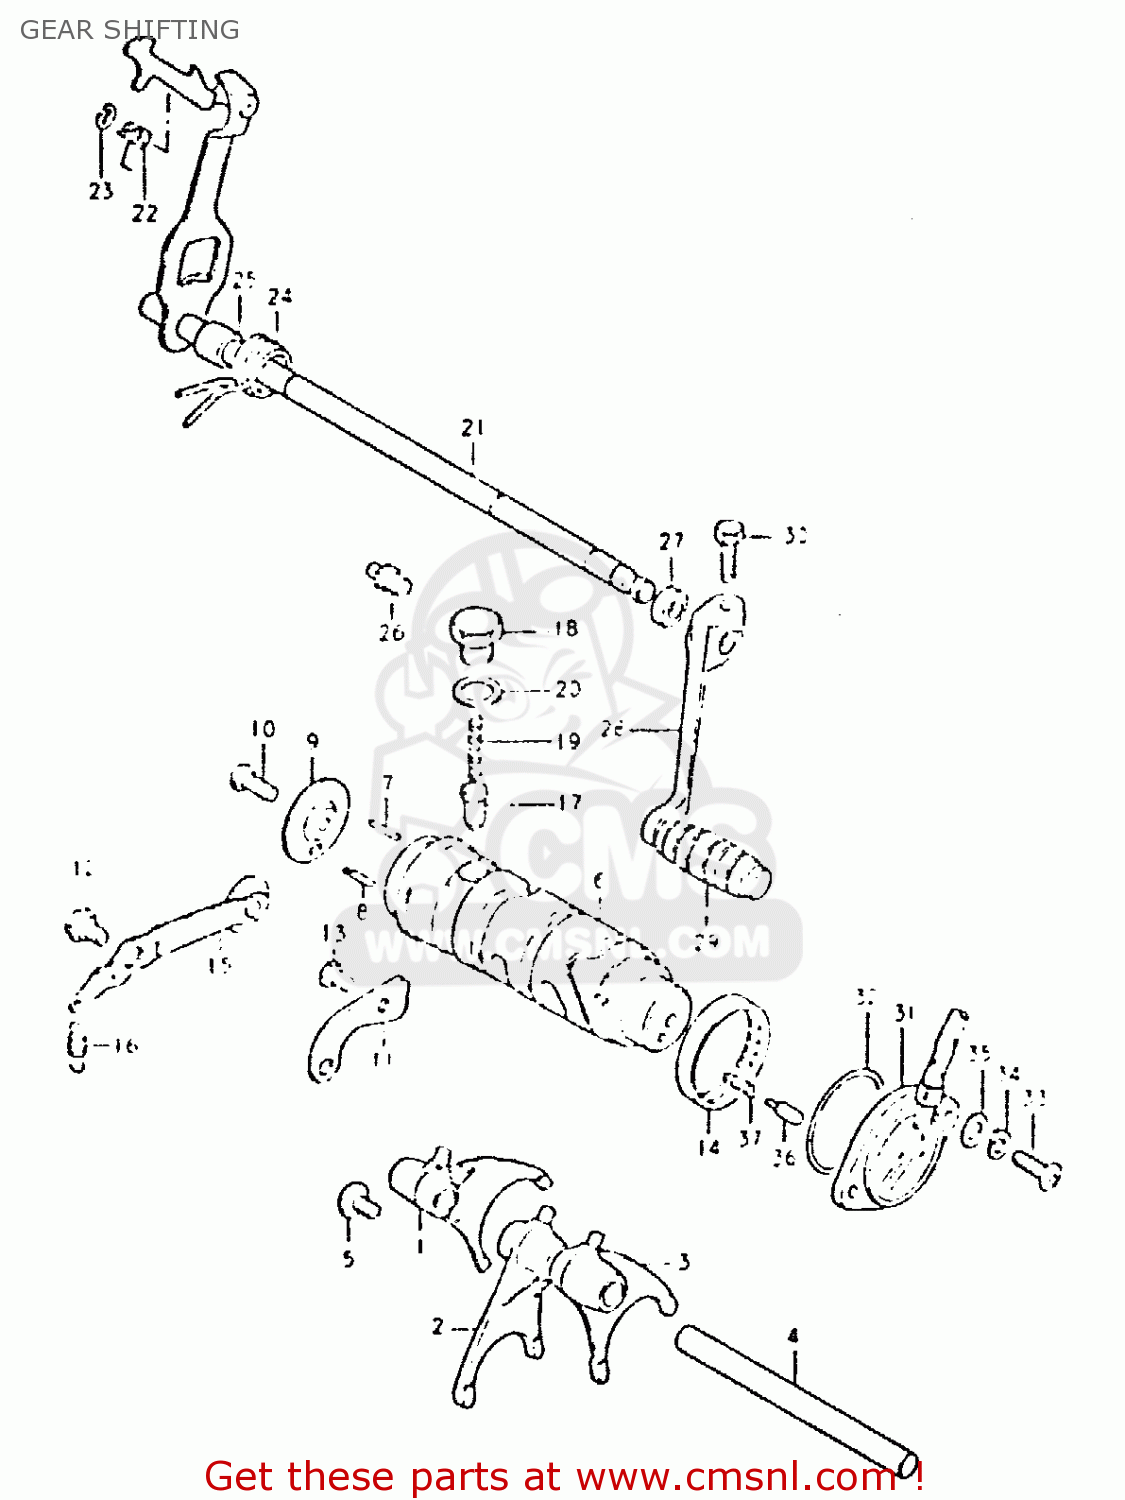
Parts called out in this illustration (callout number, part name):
1	FORK,GEAR SHIFT NO.1
2	FORK,GEAR SHIFT NO.2
3	FORK,GEAR SHIFT NO.2
4	SHAFT,GEAR SHIFT FORK
5	SCREW
6	CAM,GEAR SHIFT
7	PIN(4X18.5)
8	PIN
9	RETAINER,GEAR SHIFT CAM DR PIN
10	SCREW
11	GUIDE,GEAR SHIFTING CABLE
12	BOLT
13	BOLT, UPPER
14	BEARING(40X47X12)
15	STOPPER,GEAR SHIFT CAM NO.1
16	SPRING
17	STOPPER,GEAR SHIFT CAM NO.2
18	HOLDER,GEAR SHIFT CAM STOP SPR
19	SPRING
20	GASKET(14X19.2X2) (NAS)
21	SHAFT,GEAR SHIFT
22	SPRING
23	E RING
24	SPRING
25	SPACER(12X20X15.3)
26	STOPPER,GEAR SHIFT CAM
27	OIL SEAL
28	LEVER ASSEMBLY,GEAR SHIFTING
29	RUBBER,GEAR SHIFT PEDAL
30	BOLT
31	TERMINAL BASE ASSY,GEAR SHIFT
32	O-RING (D:2.4 ID:26.2)
33	SCREW 5X20
34	LOCK WASHER
35	WASHER
36	PIN(5X15.5)
37	SPRING
